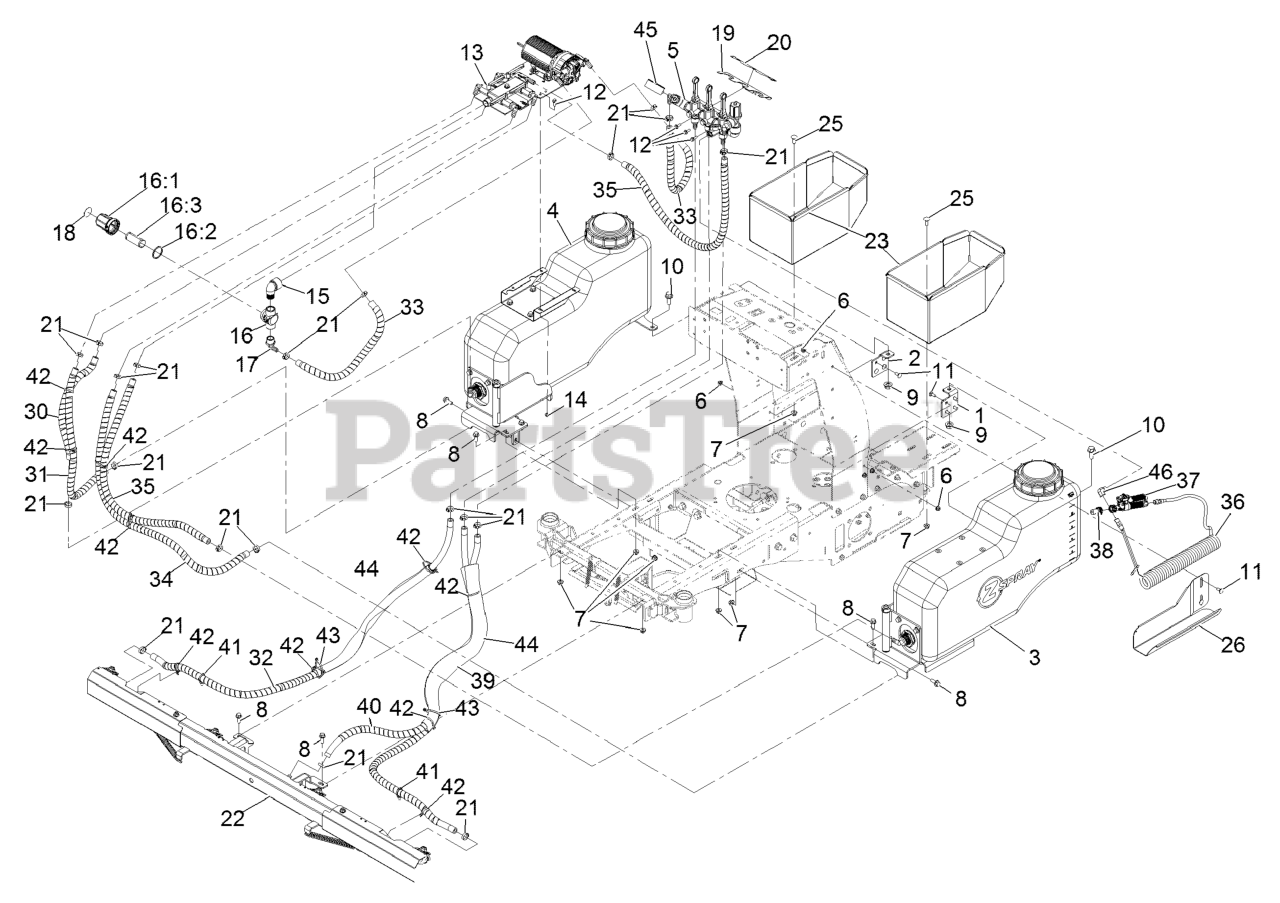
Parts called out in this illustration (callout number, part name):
1	PIN, SUPPORT, JR36
2	PIN, SUPPORT, JR36, SS, 0.188
3	ASM-TANK, LT
4	ASM-TANK, RT
5	ASM-Manifold
6	Nut-Hex Flange
7	Nut-Hex Flange
8	SCREW-HHF
9	NUT-HEX FLANGE
10	SCREW-HHF
11	SCREW-CARR
12	Screw-HHF
13	ASM, Liquid Valve
14	Nut-Hex Flange
15	ELBOW-90DEG
16	STRAINER-INLINE
16:1	BOWL-STRAINER
16:2	GASKET-HEAD, LINE STRAINE
16:3	Screen-Strainer, 50 Mesh
17	FITTING-ELBOW, 90
18	DECAL-CAP, STRAINER
19	Bracket-Manifold
20	Decal-Valve, Boom
21	CLAMP-OETIKER, 167
22	ASM-Boom, Spray
23	BOX-FERT
25	SCREW-CARR
26	TRAY, GUN, JR36
30	Hose-Spray, Wrapped
31	Hose-Spray, Wrapped
32	HOSE ASM-65,1/2,EPDM,WRAP
33	HOSE-SPRAY, WRAPPED
34	Hose-Spray, Wrapped
35	Hose-Spray, Wrapped
36	HOSE-COILED, 15 FT
37	GUN-SPRAY, SPOT
38	TIP-SPRAY, #12 SPOT
39	HOSE ASM-63,1/2,EPDM,WRAP
40	HOSE-SPRAY, WRAPPED
41	CLIP-TIE
42	TIE-CABLE
43	TIE-CABLE
44	Guard-Mesh
45	GAUGE
46	FITTING-ELBOW, 90
